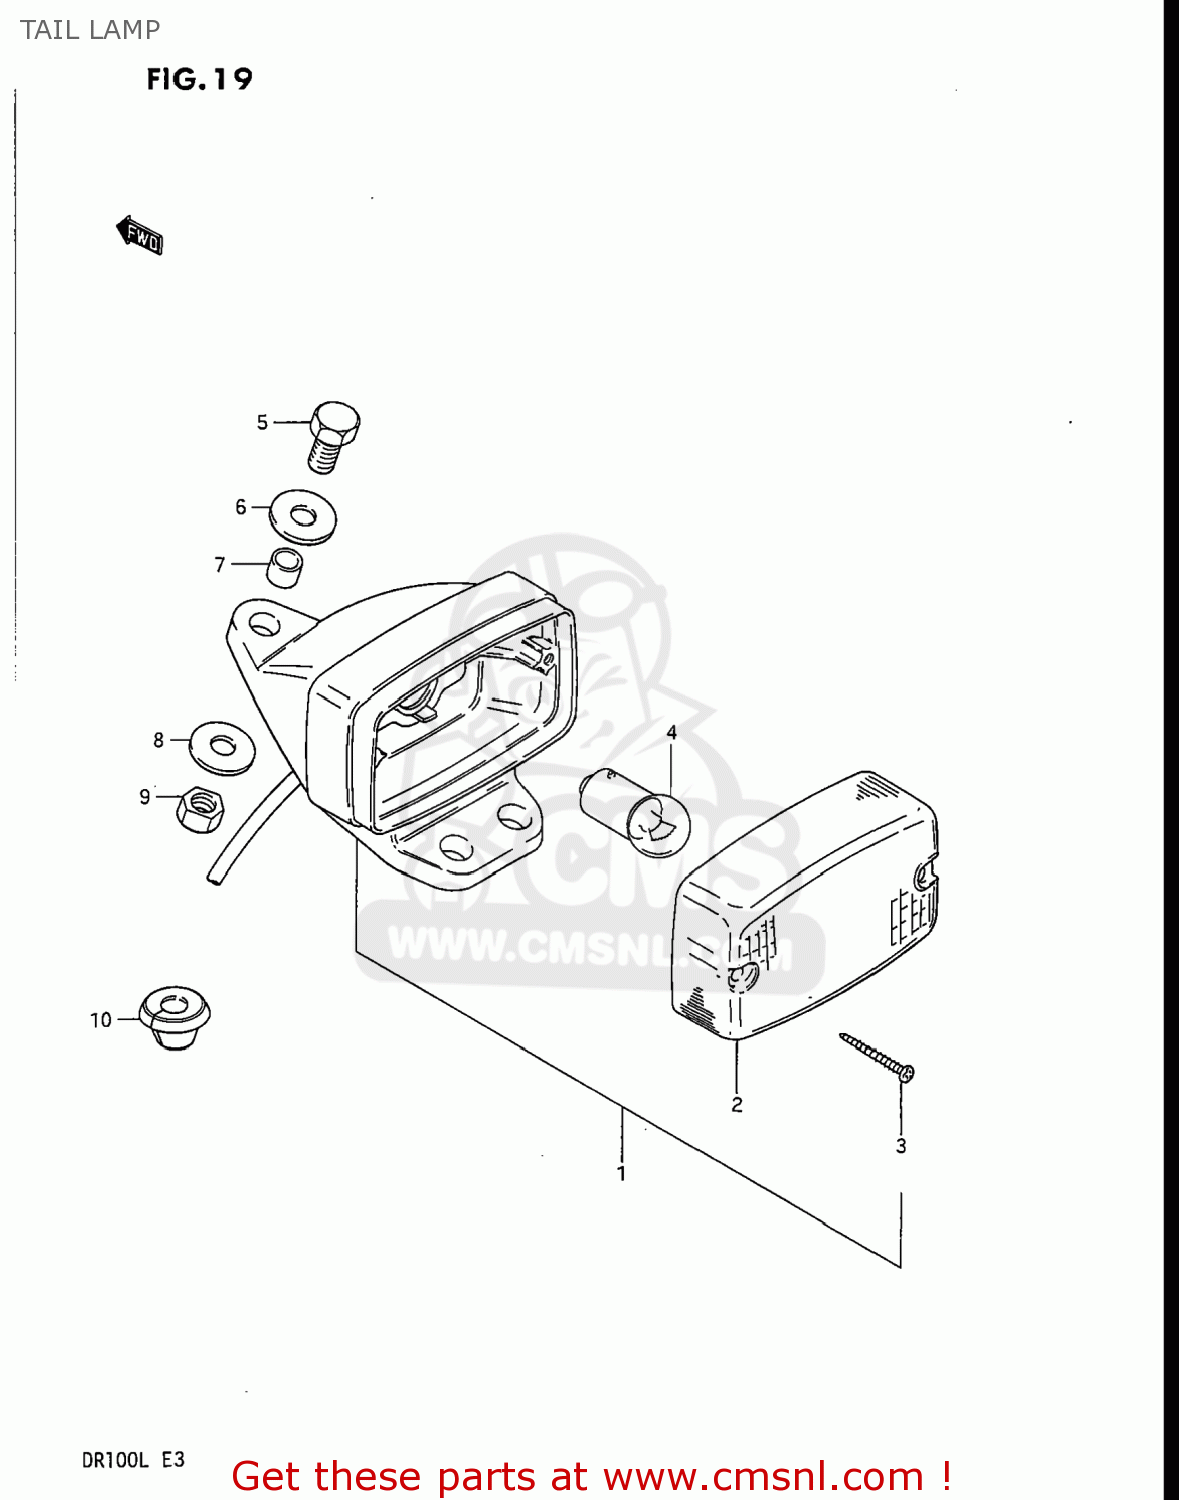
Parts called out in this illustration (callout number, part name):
1	LAMP ASSY,TAIL
2	LENS
3	SCREW
4	BULB(6V5W,TOKAI DENSO)
5	BOLT
6	WASHER
7	SPACER(6.1X9X7.5)
8	WASHER
9	NUT
10	GROMMET
